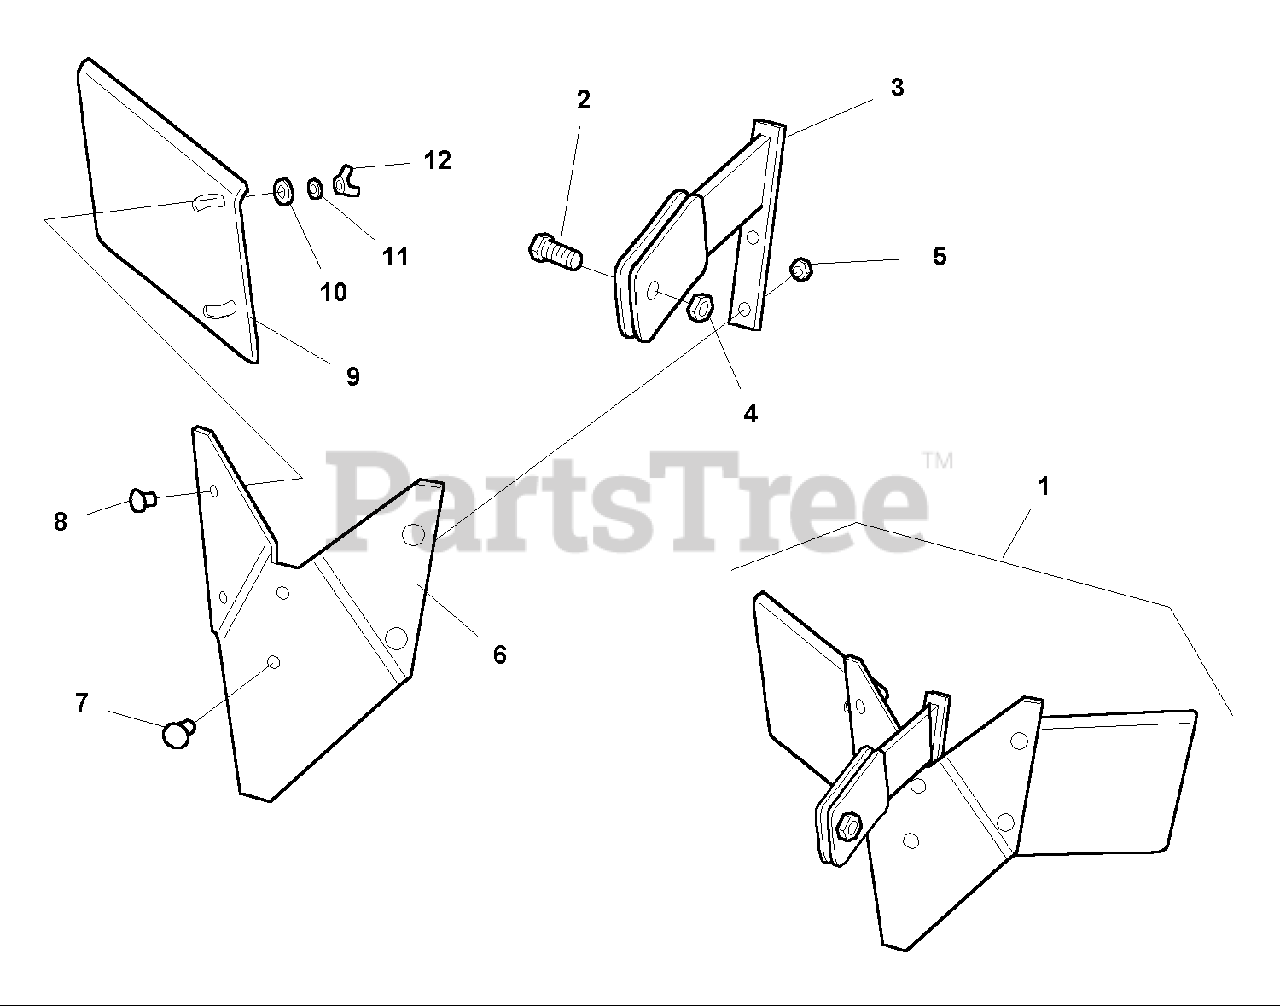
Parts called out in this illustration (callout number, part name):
1	HILLER/FURROWER, Complete (Order as Wholegood)
3	BRACKET
6	BLADE, Furrower
9	HILLER WING, Left
